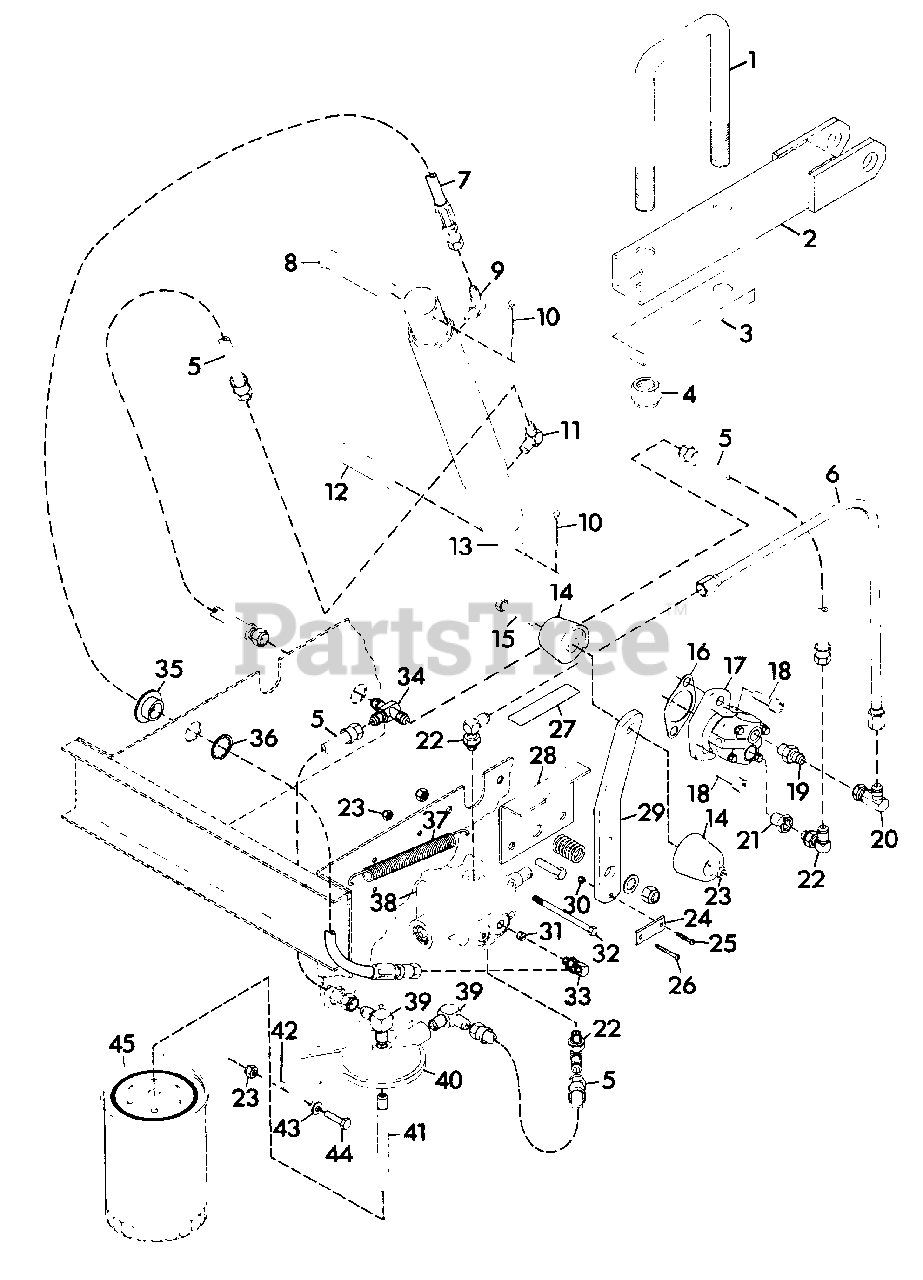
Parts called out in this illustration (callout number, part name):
1	U-BOLT
2	ARM, LIFT
3	PLATE, AXLE
4	NUT, LOCK 5/8-18
5	HOSE, HYDRAULIC
6	LINE, HYDRAULIC PUMP TO VALVE
7	HOSE, HYDRAULIC
8	PIN, CLEVIS
9	ADAPTOR
10	PIN, COTTER .125X1.25
11	ADAPTOR, HYDRAULIC
12	PIN, CLEVIS
13	CYLINDER, HYDRAULIC
14	KNOB, CONTROL
15	BOLT, HEX 1/4-20X1.50
16	GASKET, COVER PLATE
17	PUMP, HYDRAULIC
18	SCREW, CAP 3/8-16 HEX SOCKET HEAD
19	ADAPTOR
20	ADAPTOR
21	BUSHING
22	ADAPTOR
23	NUT, LOCK 1/4-20
24	STRAP, VALVE
25	SCREW, MACHINE 10-24X.75 RD HD
26	SCREW, MACHINE 10-24X1.00 RD HD
27	DECAL, HYDRAULIC LIFT
28	BRACKET, LIFT
29	LEVER, LIFT
30	NUT, LOCK 10-24
31	PLATE, FLOW RESTRICTION
32	BOLT, HEX 1/4-20X2.75
33	ADAPTOR
34	ADAPTOR, TEE
35	BUSHING, NYLON .76X1X.6 FLANGE
36	RING, RETAINING INTERNAL TOOTH
37	SPRING, EXTENSION 5.5X.5X20 RATE
38	VALVE, CONTROL
39	ADAPTOR
40	BRACKET, OIL FILTER
41	TUBE, OIL PICKUP
42	SPACER
43	WASHER, FLAT .312X.734X.065
44	BOLT, HEX 1/4-20X1.25
45	FILTER, SPIN-ON
